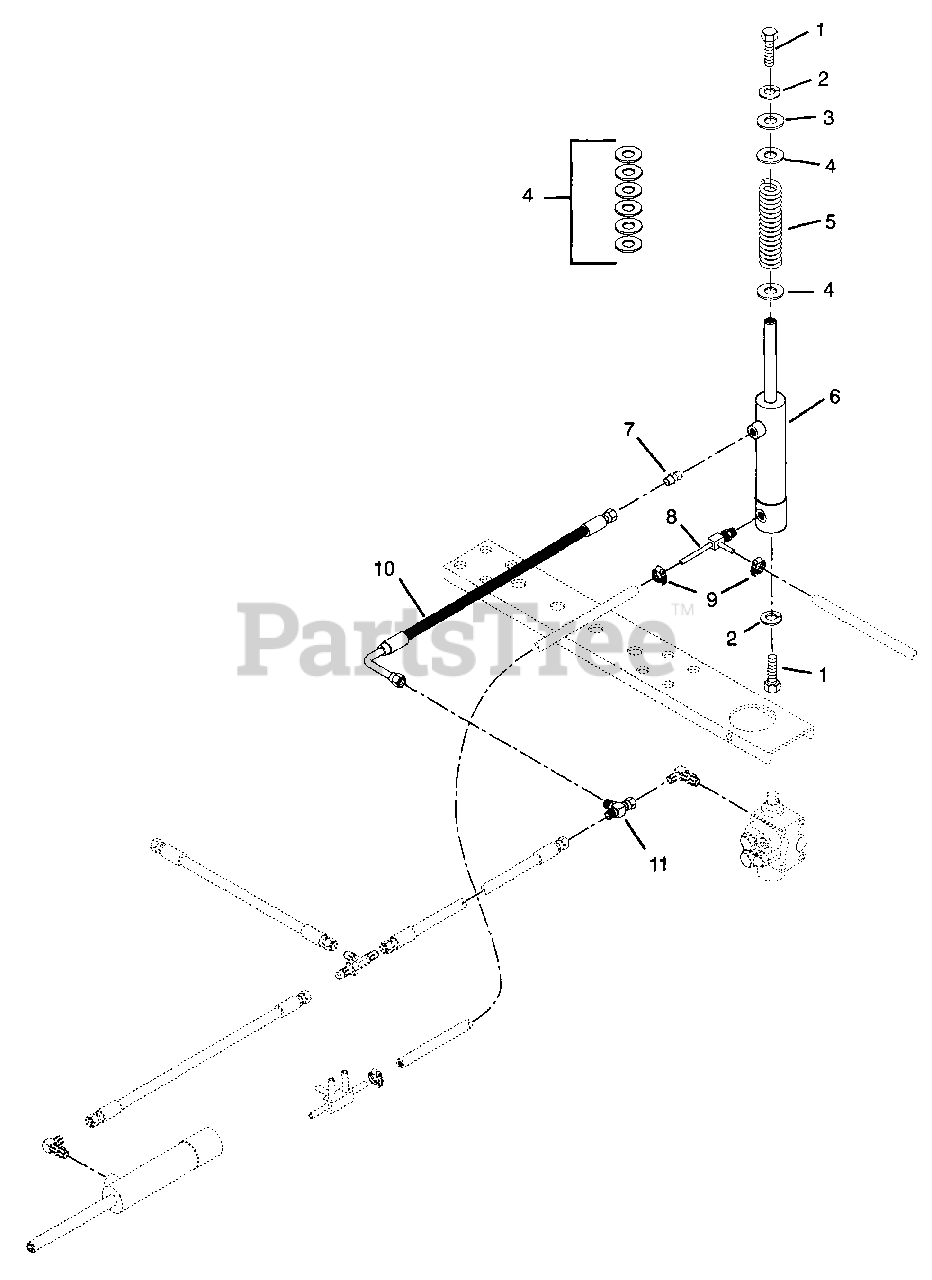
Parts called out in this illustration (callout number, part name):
1	Bolt-Hex .50-20 x 1.00 Grade 8
2	Washer-Lock .50 Reg.
3	Washer-Flat-Steel .531 x 1.250 x .100
4	Washer-Flat-Steel .700 x 1.470 x .134
5	Spring, Compression .207 x 1.25 x 6
6	Cylinder, Lift Assist
7	Adapter-Pipe .56-18 "O" Ring to .56-18
8	Adapter-Barb tee .38 to .56-18 w/ "O" Ring
9	Hose Clamp
10	Hose, PSU to Tank
11	Adapter-Pipe .56-18 to .56-18
